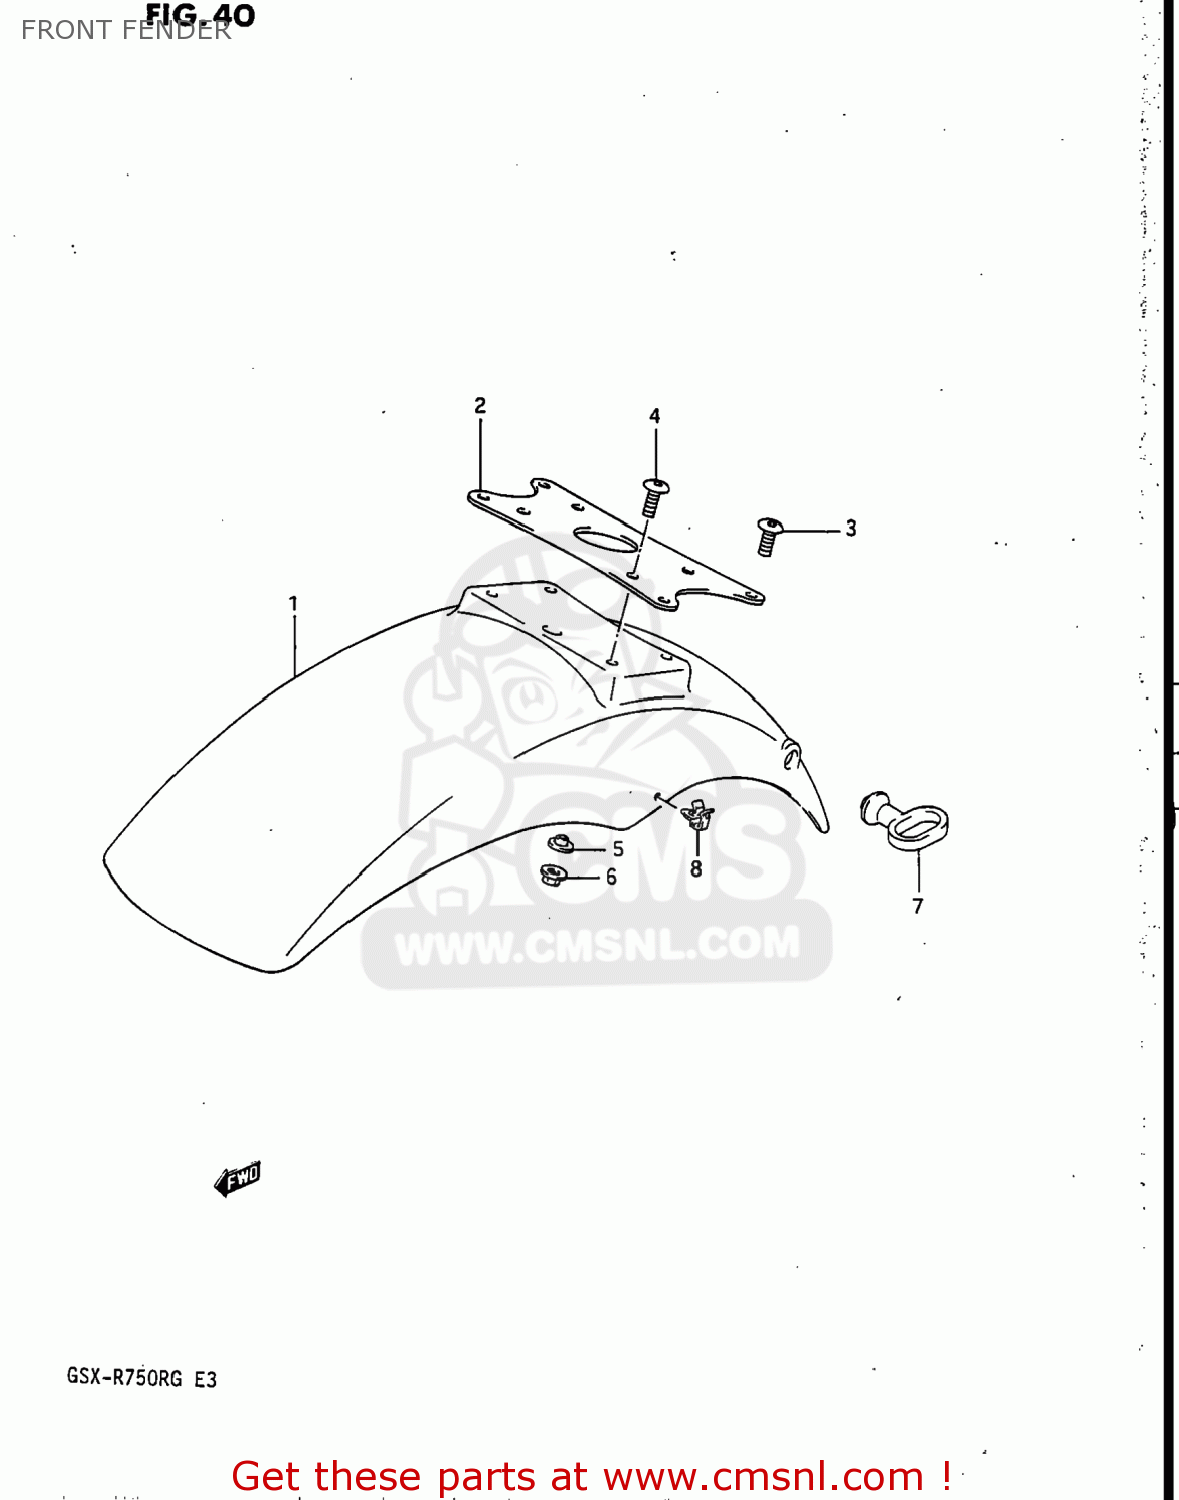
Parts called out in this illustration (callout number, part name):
1	FENDER,FRONT
2	BRACE,FRONT FENDER
3	SCREW(8X16)
4	SCREW(5X14)
5	WASHER
6	NUT
7	GUIDE,CABLE
8	CLIP
